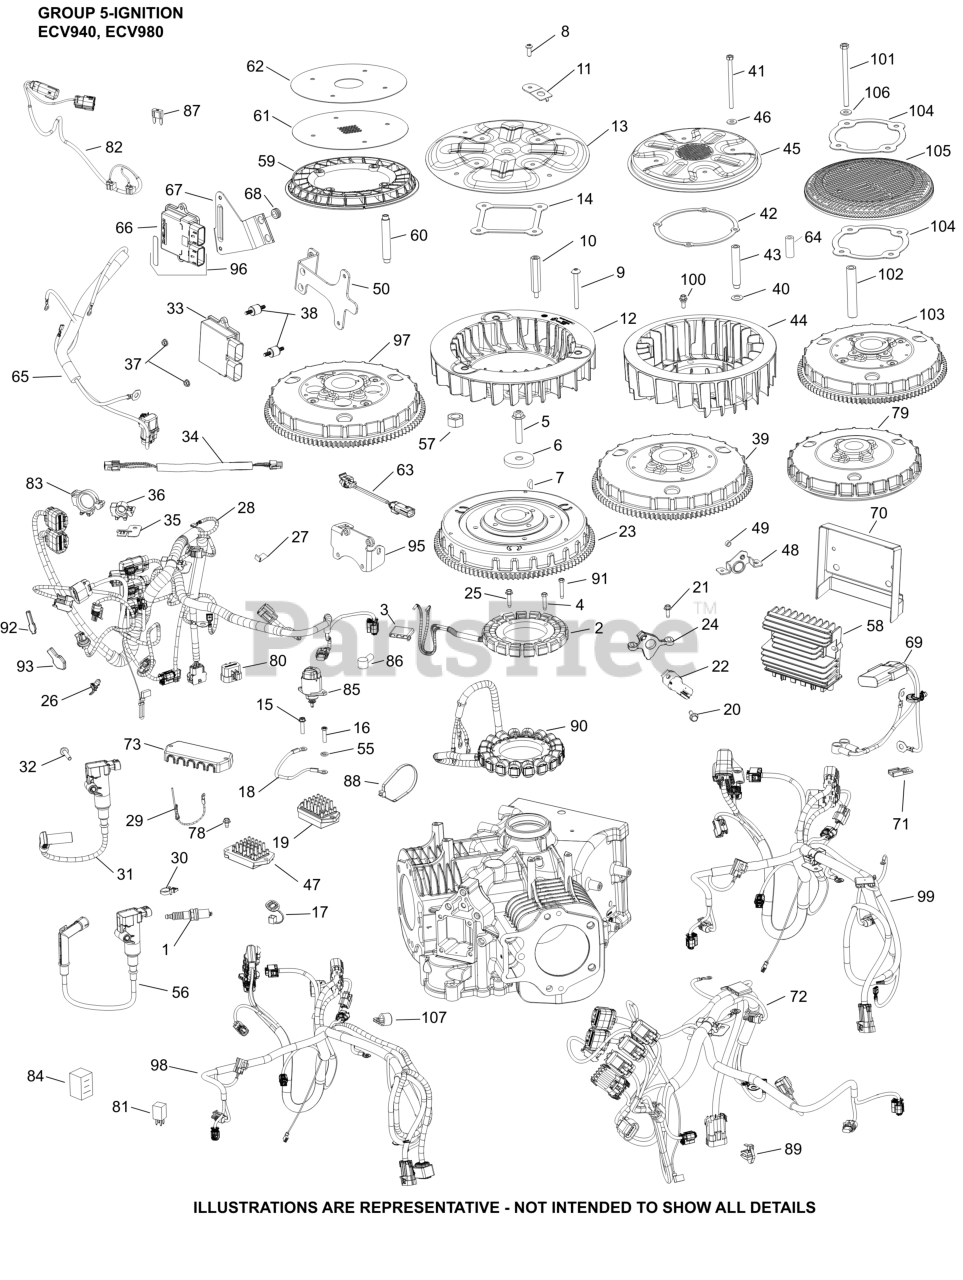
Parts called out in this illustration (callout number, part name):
1	PLUG, SPARK
2	KIT, 15 / 20 AMP STATOR
3	CONNECTOR
4	SCREW, THREAD FORMING
5	SCREW, HEX FLANGE
6	WASHER, FLAT 13/32"
7	KEY, 3/16" X 5/8"
15	SCREW, HEX FLANGE HI-LO
21	SCREW, THREAD FORMING
22	SENSOR, SPEED
25	SCREW, THREAD FORMING
26	TIE, WIRE
27	CLIP, BLOWER HOUSING
31	COIL, IGNITION - EFI
32	SCREW, HEX FLANGE
37	NUT, FLG M5X.8
38	ISOLATOR, VIBRATION STUD
47	REGULATOR, RECTIFIER (20-30AMP,FW W/OVP)
48	BRACKET, CRANK SENSOR
78	SCREW, THREAD FORMING
80	CAP, DIAGNOSTIC (8-WAY)
89	TIE, WIRE EDGE FIXED
96	MODULE, ECU MT05.3 SERVICE
98	HARNESS, WIRING (8-BAY (2), EFI-ETB)
100	BOLT, SHOULDER
101	SCREW, HEX HEAD M8 X 1.25 X 111.5
102	SPACER, GRASS SCREEN
103	FLYWHEEL, ASSEMBLY
104	RING, SUPPORT
105	SCREEN, GRASS
107	CLAMP, INSULATED
